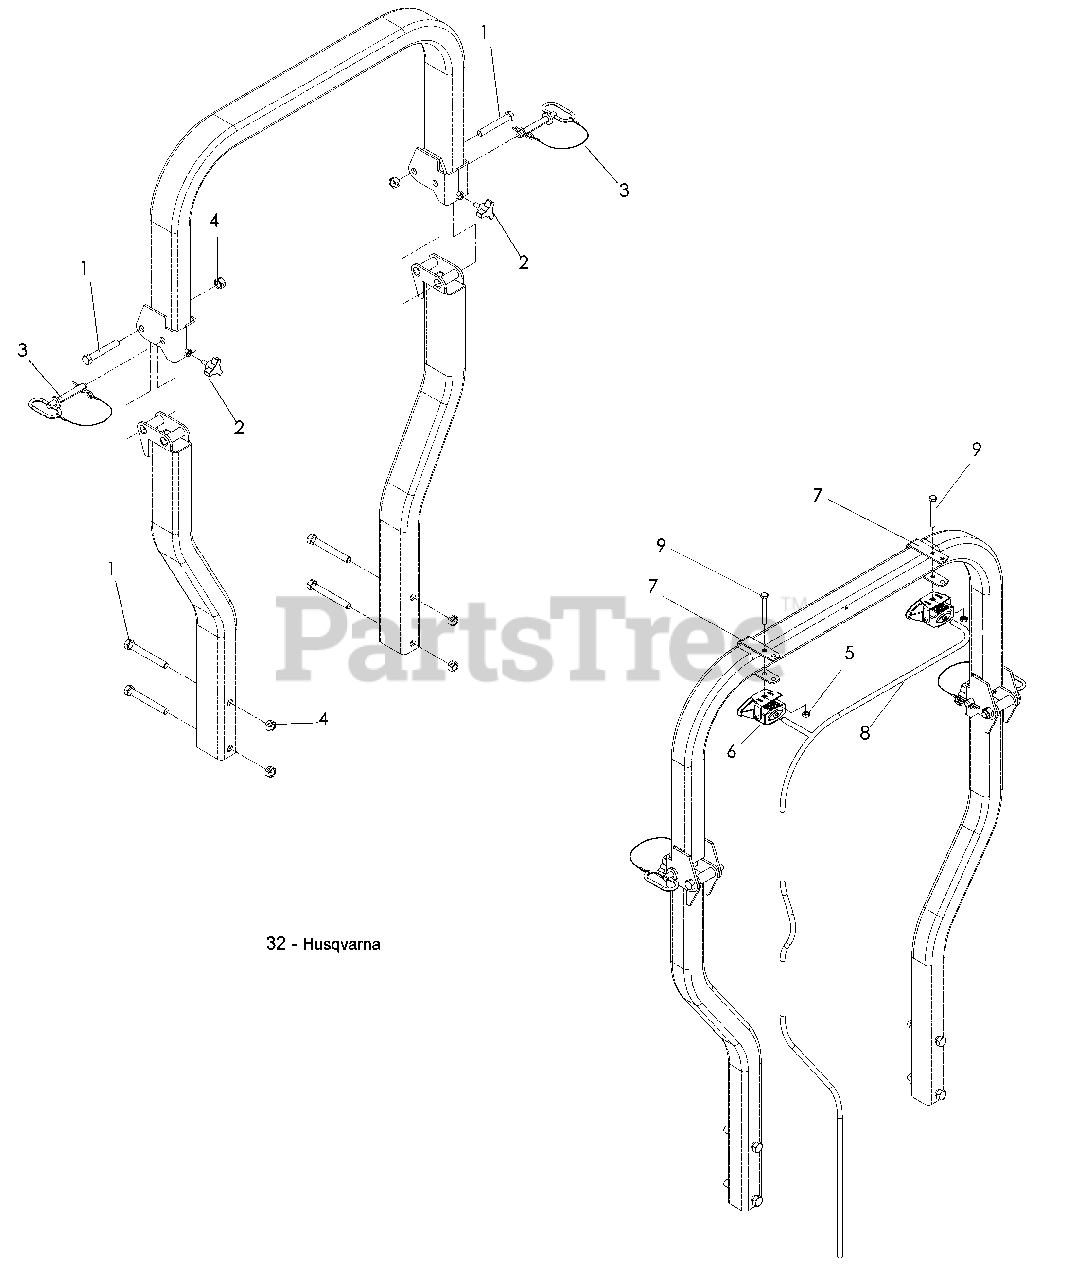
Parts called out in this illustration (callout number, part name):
1	HCS ½-13 x 3¼
2	KNOB w/STUD
3	LANYARD W/PIN ½"
4	NUT ½-13, CTRLK
5	NUT 5/16-18, JAM
6	LIGHT w/BRKT & HRDWARE
7	MOUNTING BRKT, LIGHT
8	LIGHT HARNESS
9	HCS 5/16-18 x 2½
